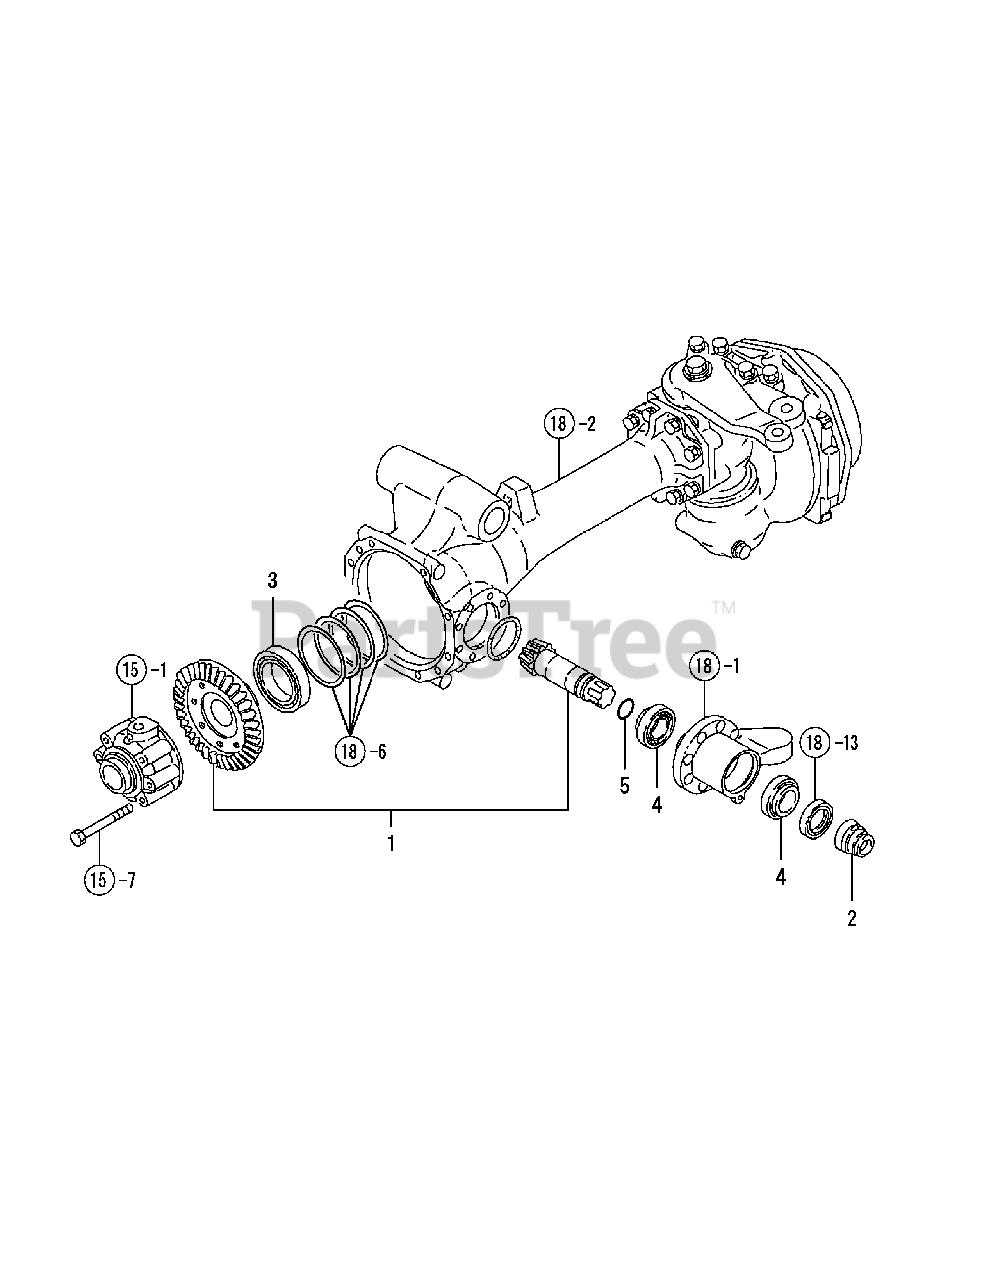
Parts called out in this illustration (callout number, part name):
1	GEAR ASSY, RING
2	SPACER, SEAL DRIVE
4	ROLLER BEARING
5	O-RING 1A S-31.5
